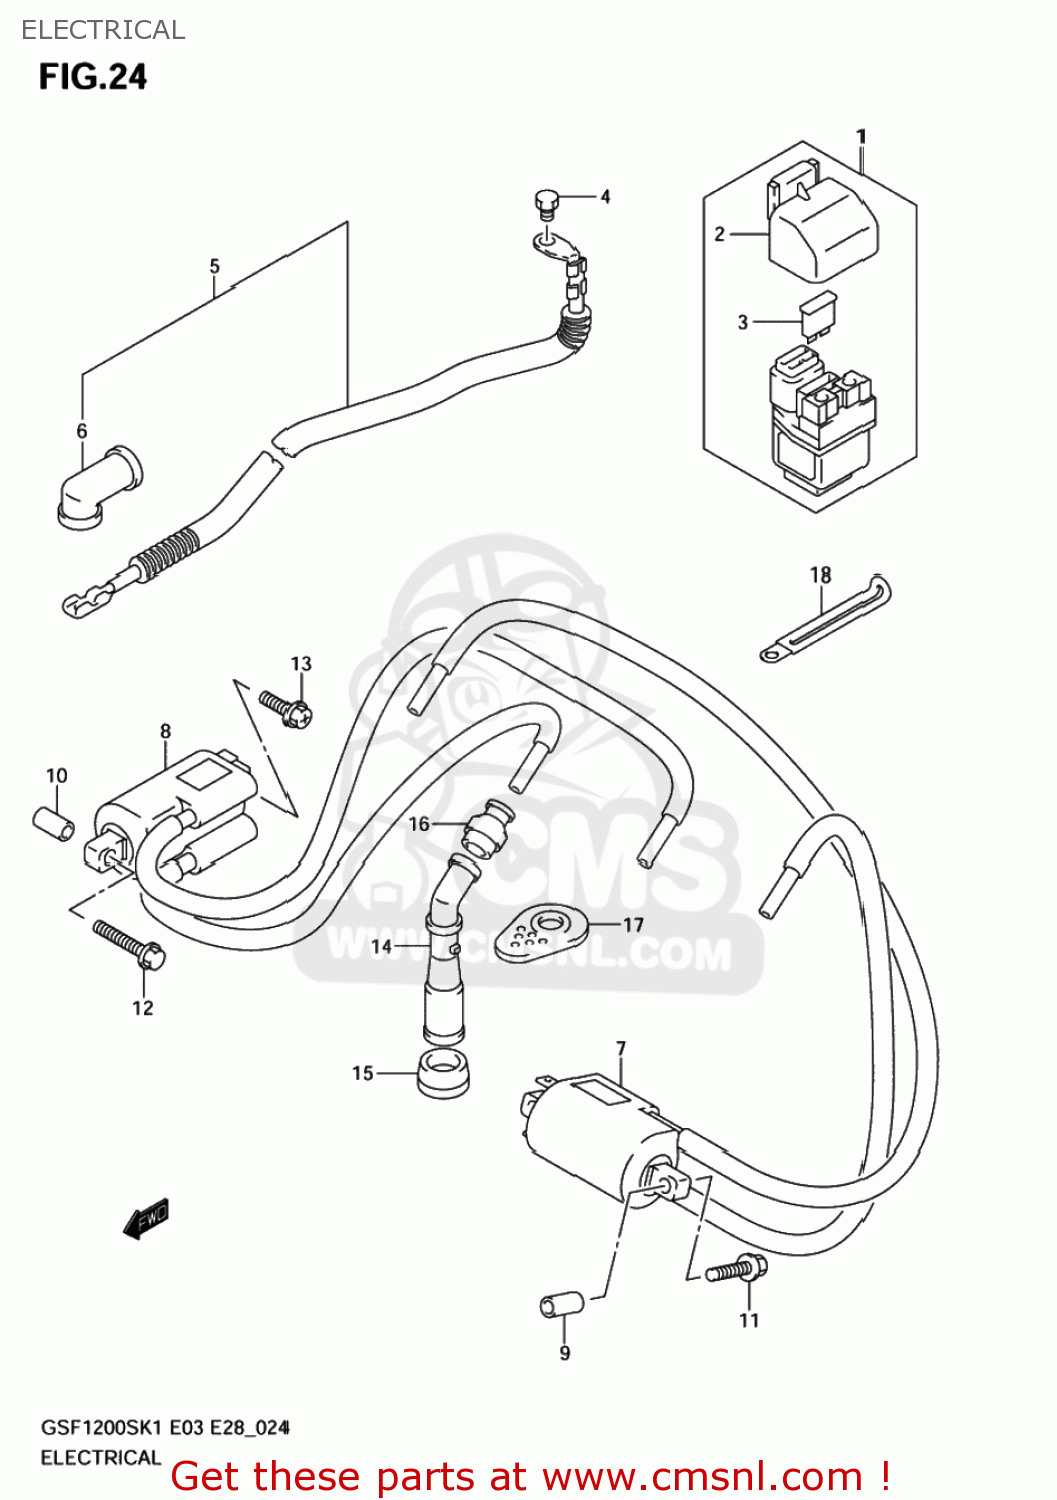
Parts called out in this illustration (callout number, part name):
1	RELAY ASSY,STARTING MOTOR
2	COVER,STARTER RELAY
3	FUSE(30A)
4	SCREW(6X8)
5	WIRE, STARTER MOTOR LEAD
6	CAP,STARTER MOTOR LEAD
7	COIL ASSY,IGNITION
8	COIL ASSY,IGNITION
9	SPACER(6X12X10)
10	SPACER(6.4X10X18)
11	BOLT
12	BOLT
13	BOLT
14	CAP,SPARK PLUG
15	SEAL,SPARK PLUG CAP
16	SEAL,HIGH TENSION CORD
17	COVER,SPARK PLUG CAP
18	CLAMP(L:65)
